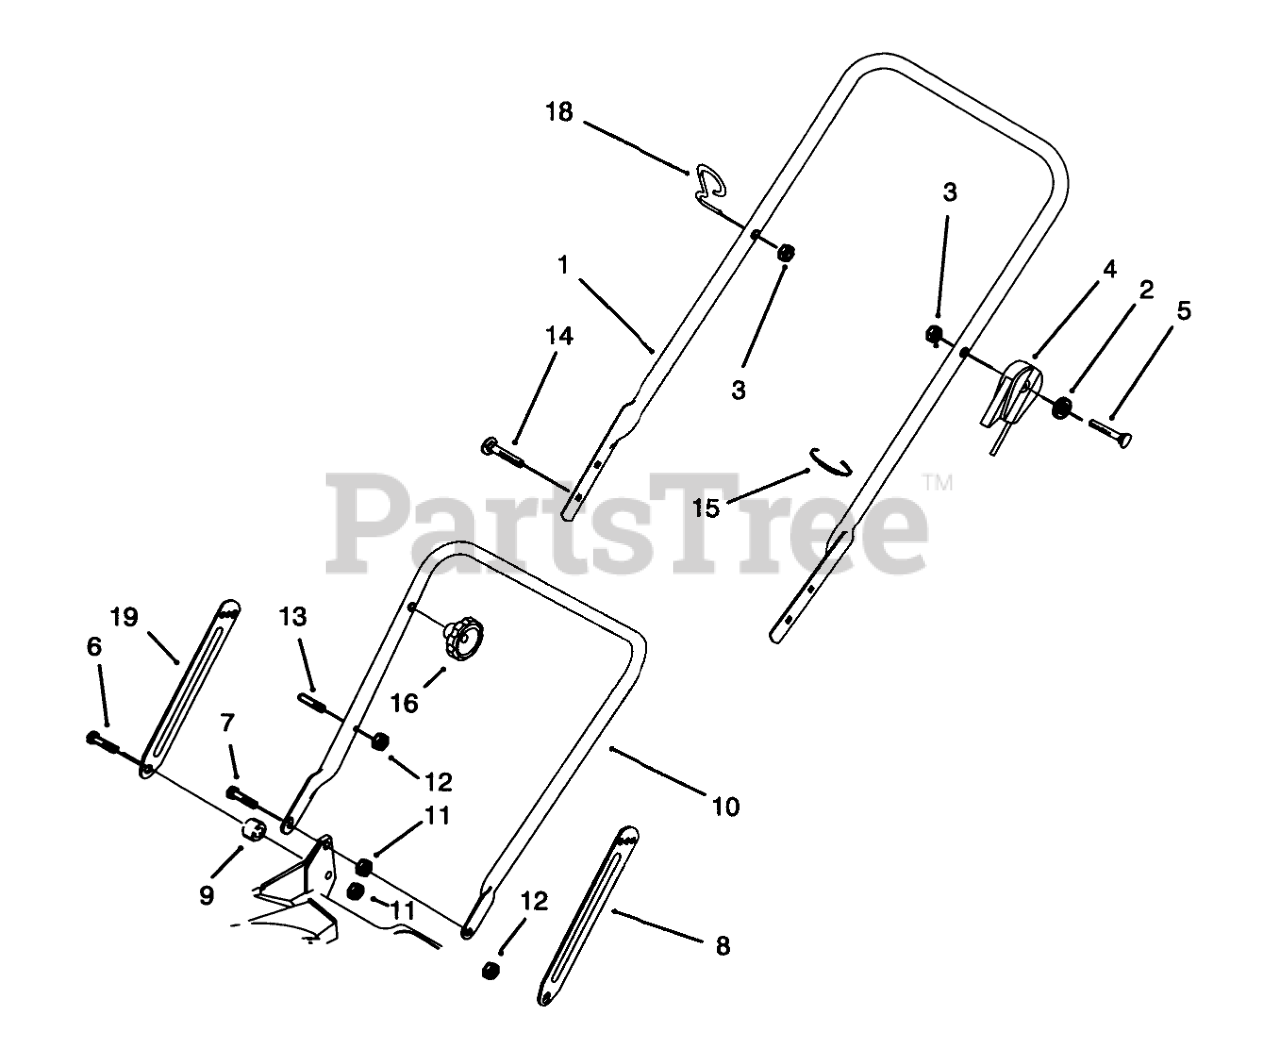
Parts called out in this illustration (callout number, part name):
1	UPPER HANDLE
2	WASHER-FLAT
3	NUT-LOCK, NI
4	THROTTLE CONTROL
5	SCREW-HH
6	SCREW-SHOULDER
7	SCREW-SHOULDER
8	LH HANDLE LATCH
9	SPACER
10	LOWER HANDLE ASM
11	NUT-LOCK, NI
12	NUT-LOCK, NI
13	HANDLE PIN
14	SCREW-HANDLE
15	TIE-CABLE
18	GUIDE-ROPE
19	RH HANDLE LATCH
